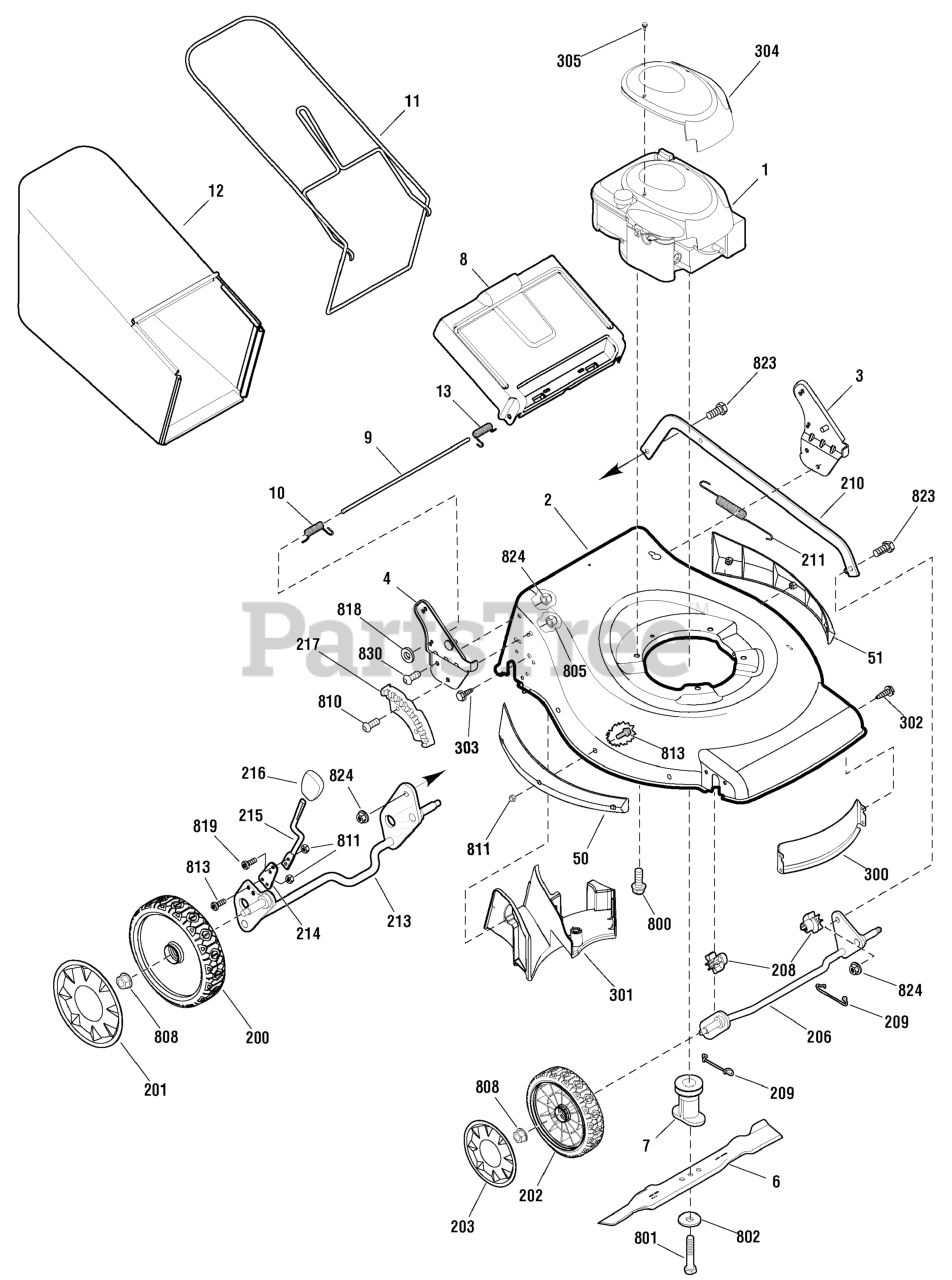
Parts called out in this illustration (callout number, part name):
1	* ENGINE, 5TP Briggs & Stratton
1	* ENGINE, 5.5TP Briggs & Stratton
2	MOWER HOUSING
3	BRACKET ASSEMBLY, Left Handle
4	BRACKET ASSEMBLY, Right Handle
6	BLADE, 19"
7	BLADE ADAPTER ASSEMBLY
8	DOOR, Rear
9	ROD, Rear Door
10	SPRING, Torsion Rear Door, Right
11	FRAME ASSEMBLY
12	BAG ASSEMBLY
13	SPRING, Torsion Rear Door, Left
50	SIDE GUARD, Right
51	SIDE GUARD, Left
200	WHEEL, Rear
201	HUBCAP, Rear
202	WHEEL, Front
203	HUBCAP, Front
206	CROSSBAR ASSEMBLY, Front
208	BUSHING, Front Crossbar
209	SPRING, Clip Crossbar
210	LINK, Single Lever
211	SPRING, Extension
213	CROSSBAR, Rear
214	SPRING, Adjuster
215	LEVER, Height Adjustment
216	KNOB, Adjuster
217	BRACKET, Height Adjuster
300	BAFFLE, Front, 19
301	BAFFLE, Rear, 19
302	SCREW, Pan Head, Taptite, 1/4-20 x 1/2
303	SCREW, Pan Head, Taptite, 1/4-15 x 5/8
304	SHROUD/LABEL
305	SCREW, Hex Washer Head
800	SCREW, Hex Head, 3/8-16 x 1
801	BOLT, Blade, 3/8-24 x 2
802	WASHER, Belleville
805	NUT, Nylock, M8 x 1-1/4
808	NUT, Flange, 3/8-16
810	BOLT, Hex Key Head
811	NUT, Nylock
813	SCREW, Torx Head, M5 x .8 x 14mm
818	PUSHNUT, 1/4
819	SCREW, Torx Head, M5 x .8 x 12.5mm
823	BOLT, Shoulder, 5/16-18 x 1
824	Nut, Flange, 5/16-18
830	SCREW , 5/16-18 x 3/4
1000	DECAL KIT
